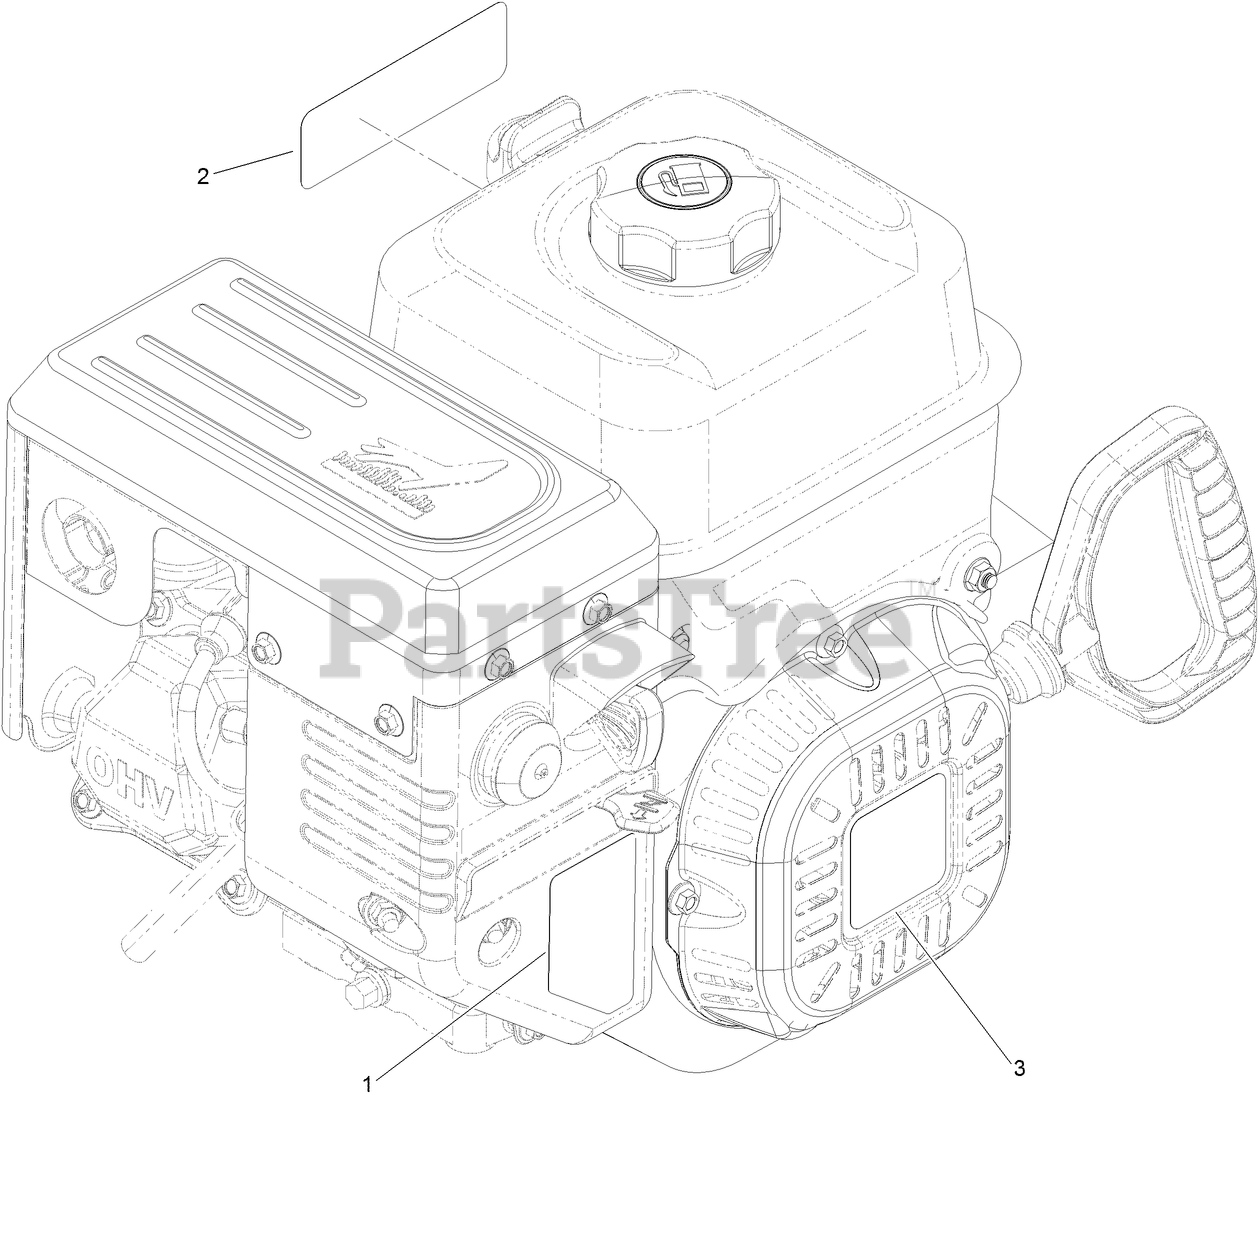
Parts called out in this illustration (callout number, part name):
1	DECAL-CONTROL, ENGINE
2	DECAL-ENGINE, SERIES G210
3	DECAL-RECOIL, G210
